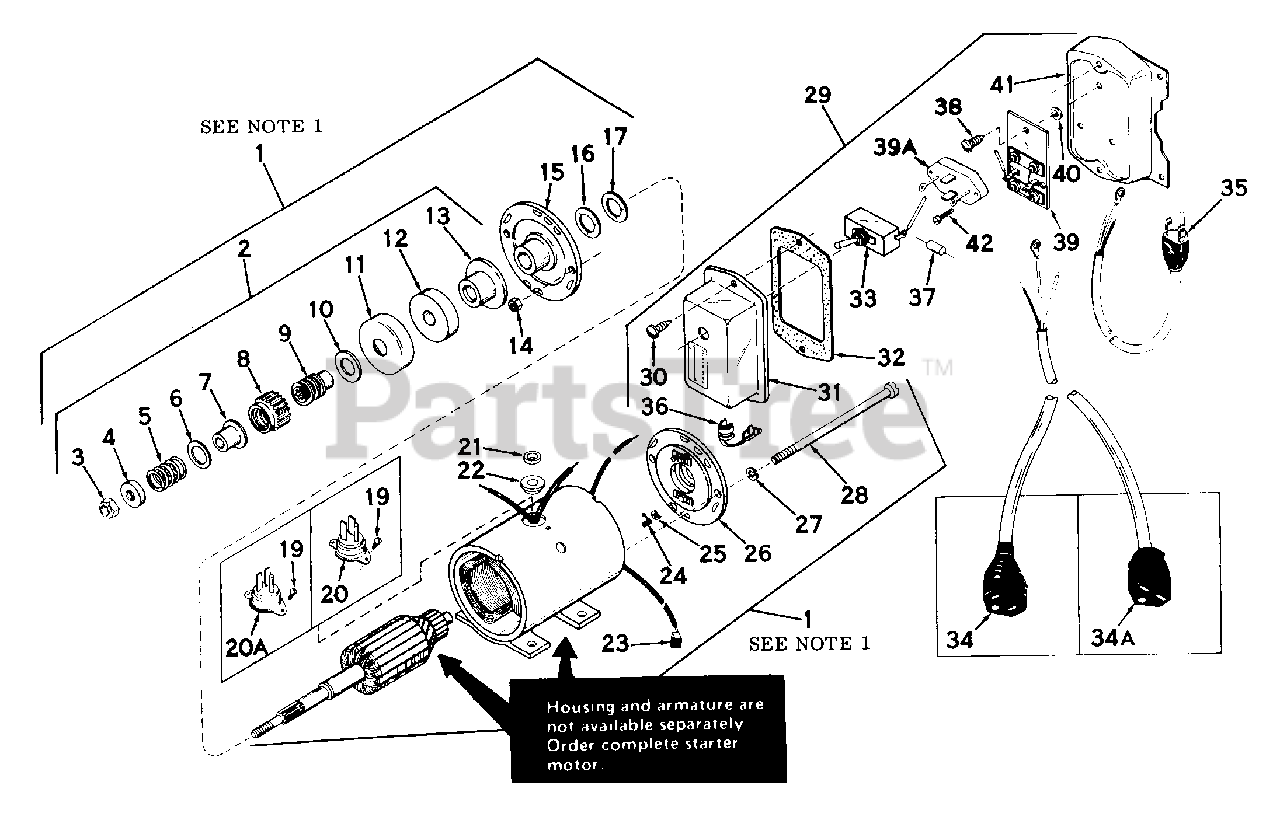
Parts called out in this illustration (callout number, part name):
1	"Motor, Cranking
2	Drive Assy.
3	Nut, Elastic stop
4	Stop, Pinion gear
5	Spring, Anti-drift
6	Washer, Pinion gear
7	Sleeve, Anti-drift spring
8	Gear, Pinion
9	Shaft, Screw
10	Washer, Thrust
11	Cup, Cushion
12	Cushion, Rubber
13	Washer, Thrust
14	Nut, Securing
15	Cap Assy., Drive end
16	Washer, Spacing (.010 thick)
16	Washer, Spacing (.020 thick)
16	Washer, Spacing (.005 thick)
17	Washer, Nylon
19	Screw, Fastening
20	Receptacle (Standard, parallel blades )
21	Washer, Spacing
22	Bushing, Insulation
23	Brush, Commutator
24	Spring, Brush
25	Insulation, Spring
26	Cap Assy., Commutator end
27	Washer, Lock
28	Bolt, Thru
29	Rectifier Assy. (Standard plug, for p arallel
30	Screw, Fastening
31	Cover, Rectifier
32	Gasket, Cover
33	Switch, Toggle
34	Cable Assy., D.C. output (Standard pl ug, for
35	Cable Assy., A.C, input
36	Bushing, Strain relief
37	Thyrector
38	Screw, Fastening
39	Base Assy., Rectifier
40	Washer, Spacing
